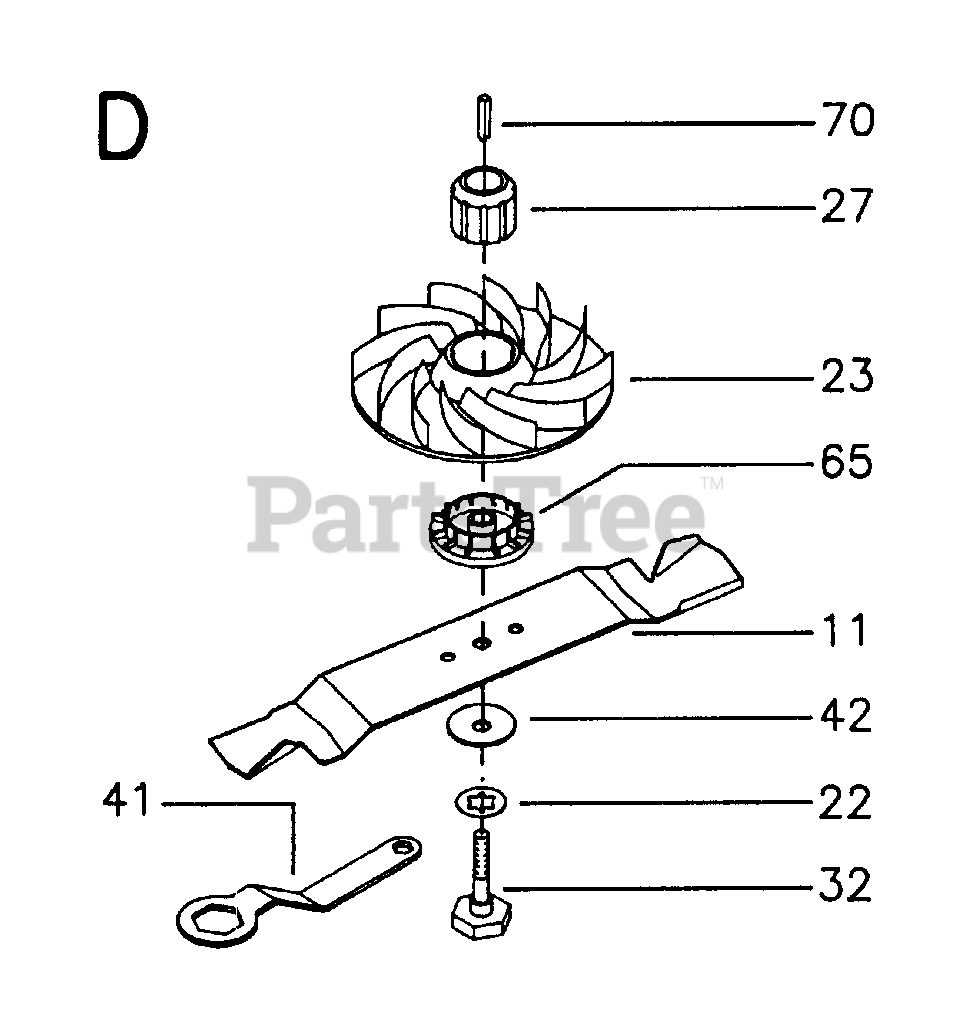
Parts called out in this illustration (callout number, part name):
23	IMPELLER
42	DISC SPRING
65	BLADE ADAPTOR
